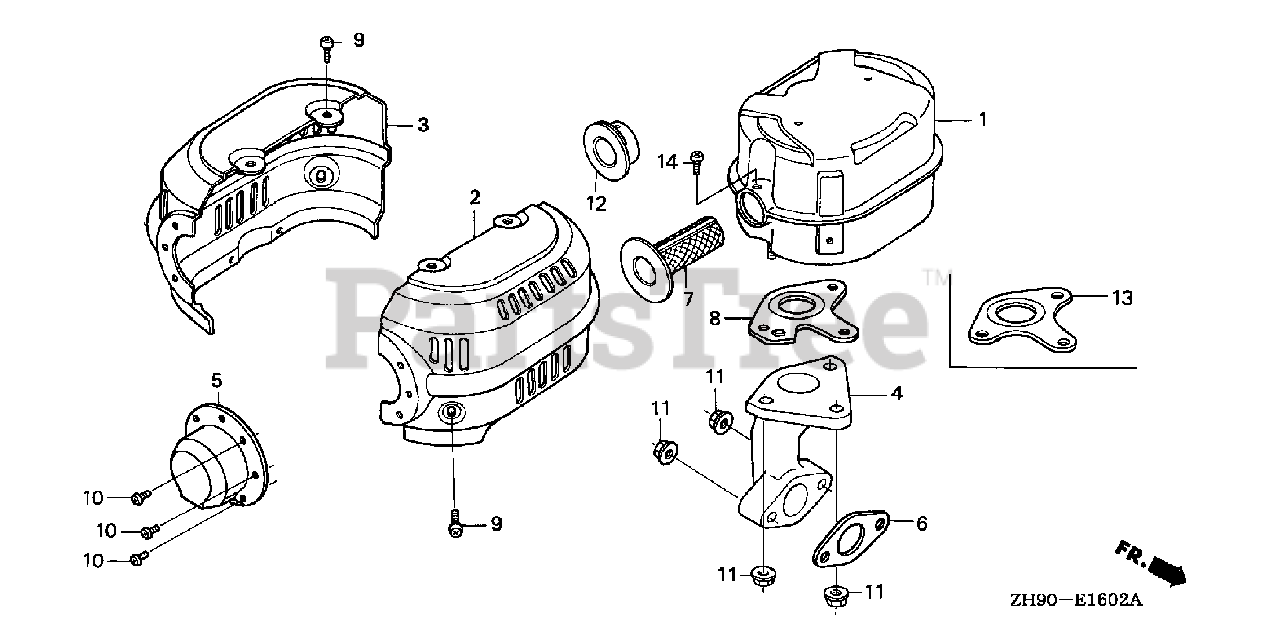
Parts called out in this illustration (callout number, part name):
1	MUFFLER
2	PROTECTOR, R. MUFFLER (STD)
3	PROTECTOR, L. MUFFLER (STD)
4	PIPE, EX.
5	CAP, MUFFLER
6	GASKET, EX. PIPE
6	GASKET, EX. PIPE (WACKER)
7	ARRESTER, SPARK
8	GASKET, MUFFLER (ARRESTER)
9	SCREW, TAPPING (5X8)
10	SCREW, TAPPING (4X6)
11	NUT, FLANGE (8MM)
14	SCREW, TAPPING (5X8)
